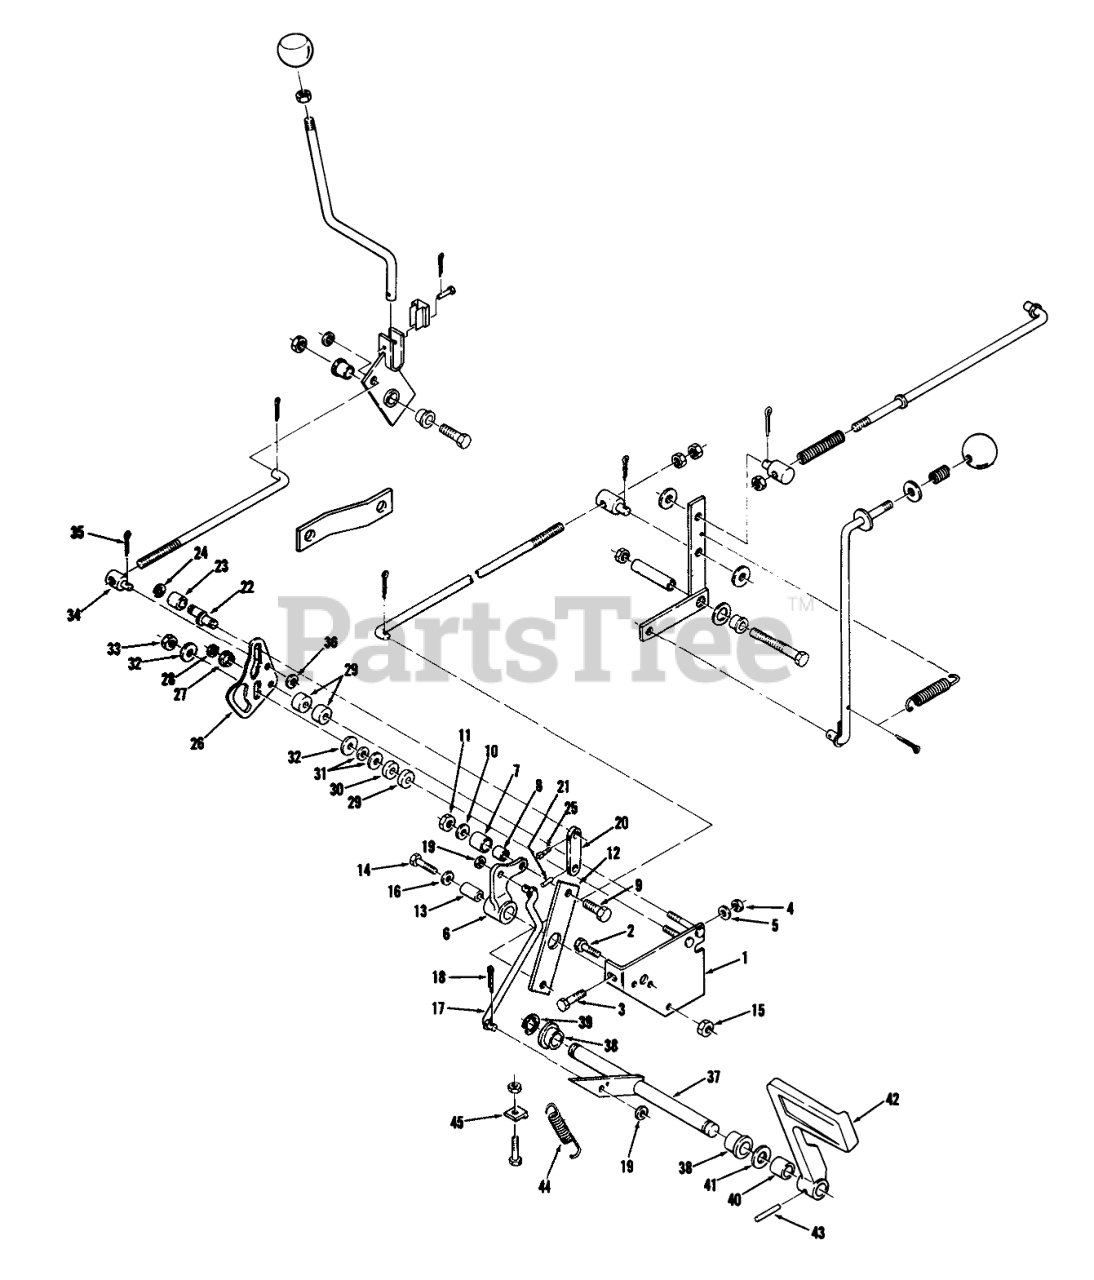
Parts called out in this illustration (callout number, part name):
1	Assy-Plate
2	Screw
3	HHCS
4	Nut
5	WASHER 5/16 SAE
6	Lever-Neutral Return
7	BEARING-CAM RETURN
8	SPACER
9	BOLT
10	Washer
11	Nut
13	Spacer
14	Bolt
15	NUT
16	WASHER
17	ROD ASSY
18	Cotter Pin
19	Washer
20	Arm-Speed Control
21	PIN-ROLL 1/4 X 1 1/4
22	ECCENTRIC-CAM FOLLOW
23	Spacer
24	E RING
25	SET SCREW
26	Cam-Speed Control
27	CAM-SPACER
28	Nut
29	Spacer
30	SPACER
31	WASHER-SPRING DISC
32	FRICTION WASHER
33	Nut Conlok 3/8-16
36	Washer
37	Assy-Shaft
38	BEARING
39	E-RING
40	Spacer
41	WASHER
42	Brake Pedal
43	PIN-ROLL, SPIROL
44	SPRING-EXTENSION
45	CLIP - SPRING
